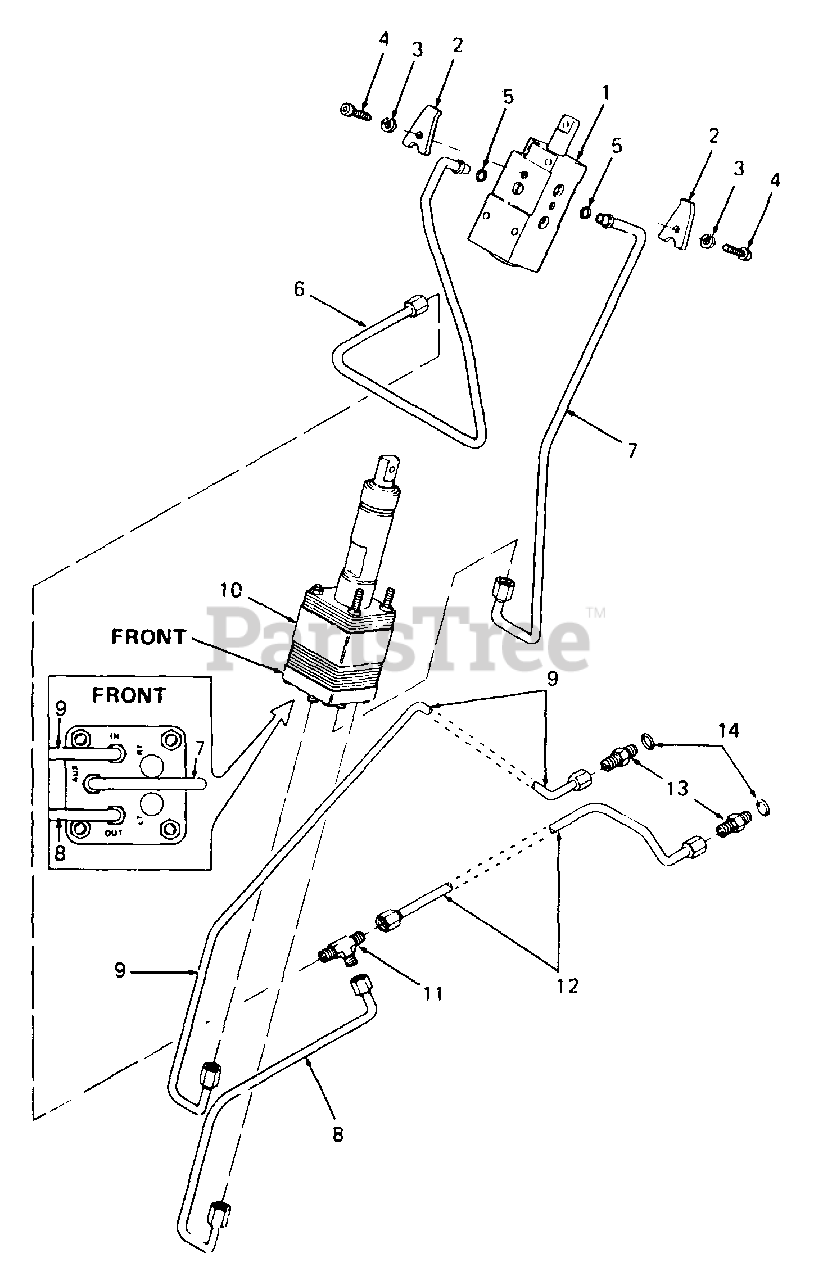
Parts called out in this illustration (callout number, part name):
1	Valve, Lift
2	Clamp, Single
3	Washer, Lock, 1/4
4	Screw, Socket Hd Cap, 1/4-20 x .62 Lg GR8
5	O-Ring, .301 x .070 Dia
6	Tube Assy, P.S. Return - Upper
7	Tube Assy, P.S. Aux
8	Tube Assy, P.S. Return
9	Tube Assy, P.S, Inlet
10	Power Steering Box w/Flat
11	T-Fitting
12	Tube Assy, P.S. Return - Lower
13	Connector, 37 Deg Tube
14	O-Ring, 3/8 OD Tube
